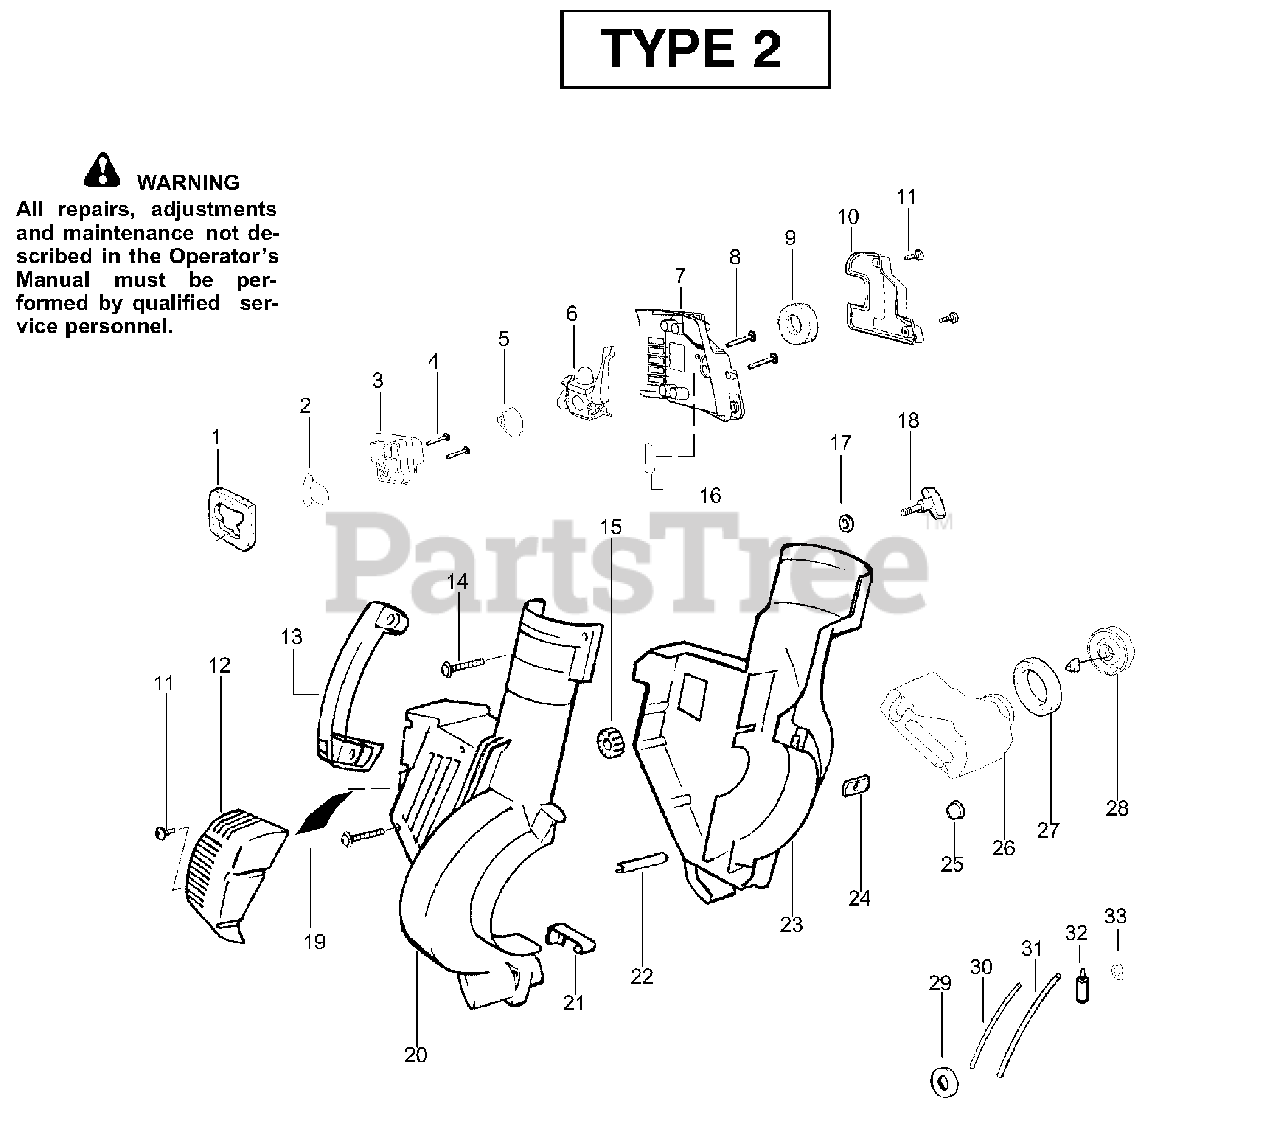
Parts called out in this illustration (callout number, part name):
1	Air Dam (kit)
2	Gasket-Adapter (kit)
3	Carburetor Adaptor
5	Gasket-Carburetor (kit)
6	Kit-Carb Ass'y (C1Q-W11)
6	Kit-Carb Ass'y (C1Q-W11C)
8	Screw-Carb.
9	Filter-Air
10	Cover-Air Filter
12	Guard-Muffler
15	Isolator
16	Foam 25.4mm (kit)
18	Knob-Tube Clamp
19	Reflector-Heat (kit)
20	Housing-Right
21	Spring-Cover Latch
22	Guide-Starter Rope
23	Housing-Left
25	Isolator-Crankcase
26	Assy-Fuel Tank
27	Gasket-Fuel Tank
28	Fuel Cap w/Retainer
29	Grommet-Shroud
30	Kit-Line Carb/Purge
31	Kit-Line Tank/Purge
32	Assy-Fuel Pick-up
33	Grommet-Fuel line (kit)
